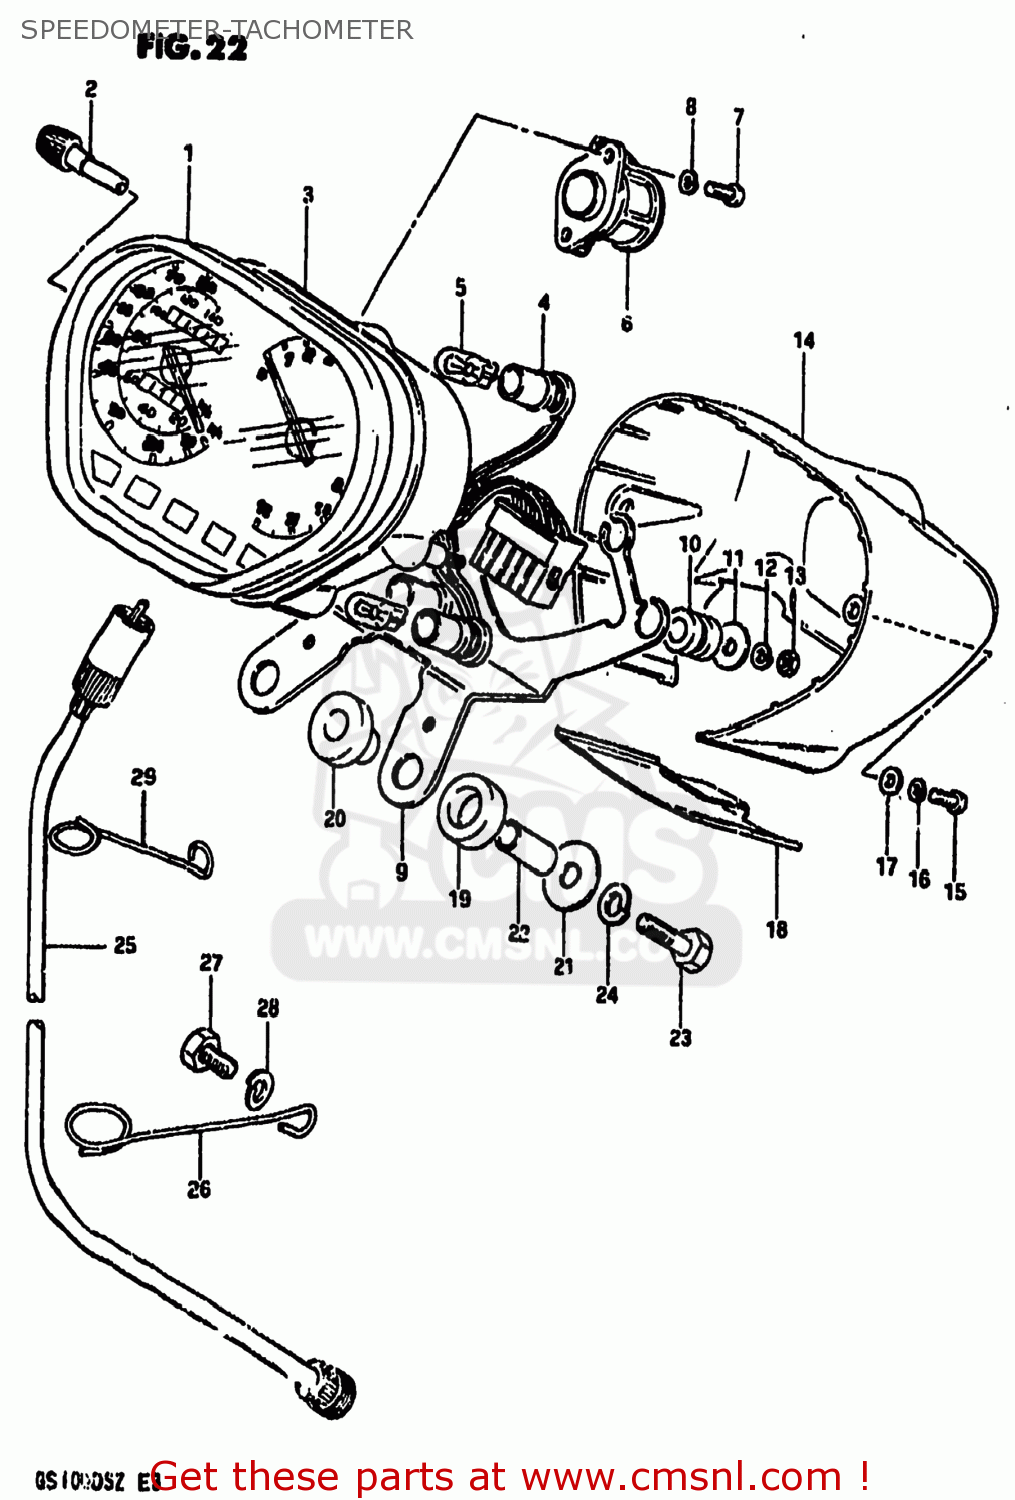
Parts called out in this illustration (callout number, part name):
2	KNOB,TRIP METER
3	CUSHION
4	SOCKET
5	BULB(12V3.4W,T10)
6	GEAR BOX,SPEEDOMETER
7	SCREW 4X10
8	LOCK WASHER
9	BRACKET,METER
10	CUSHION
11	WASHER,COMBINATION METER
12	LOCK WASHER
13	NUT
14	COVER,LWR
15	SCREW
16	LOCK WASHER
17	WASHER
18	PLATE,SPEEDOMETER
19	CUSHION
20	CUSHION
21	WASHER (6.5X24X1.6)
22	SPACER (6.1X8X15.5)
23	BOLT
24	LOCK WASHER
25	CABLE ASSEMBLY,SPEEDOMETER
26	CLAMP,SPEEDOMETER CABLE
27	BOLT, UPPER
28	WASHER
29	GUIDE,SPEEDOMETER CABLE UPR
